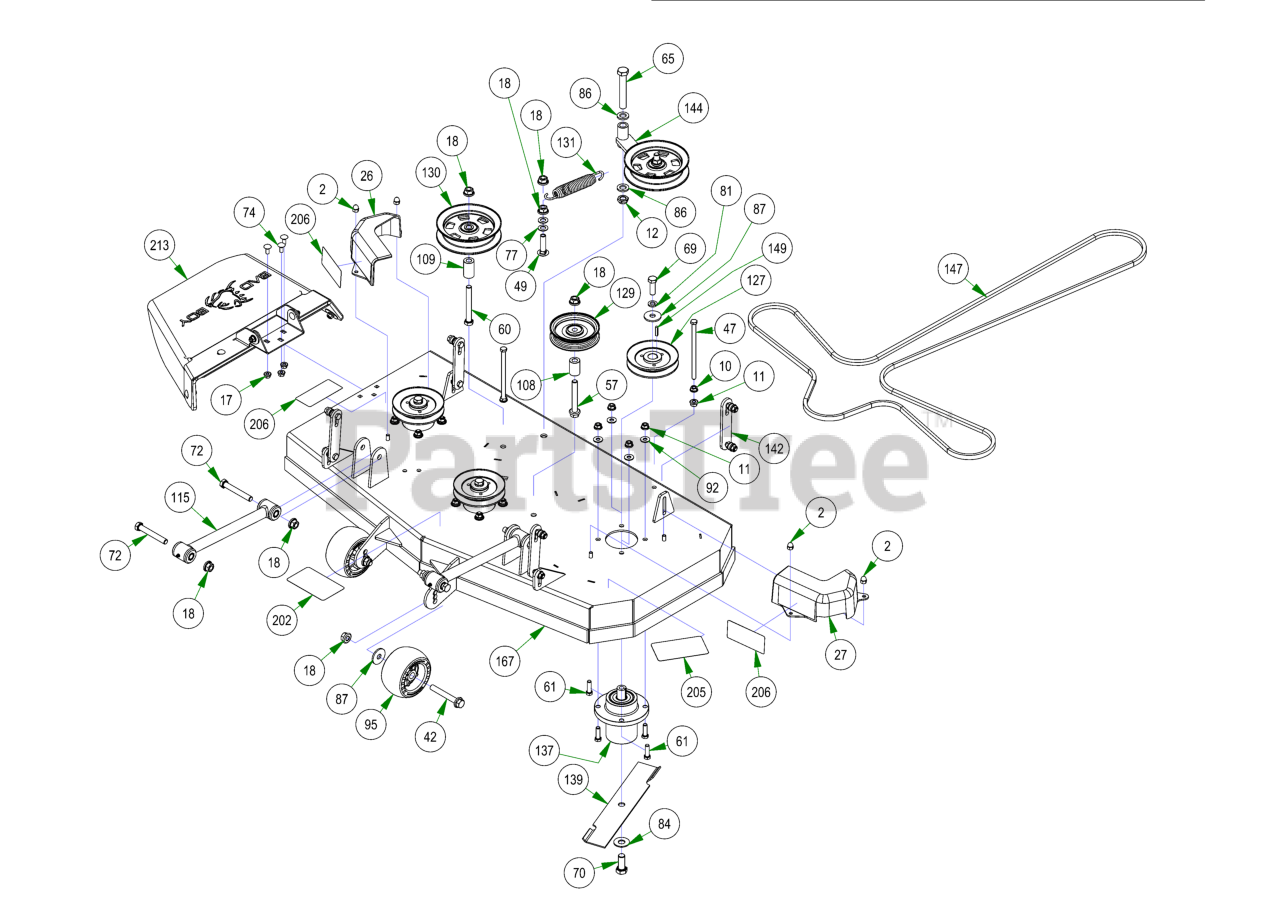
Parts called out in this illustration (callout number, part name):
2	5/16-18 ACORN NUT HIGH-CROWN ZC
10	3/8-16 HEX SERRATED FLANGE NUT HARD/ZINC
11	3/8-16 NYLON INSERT FLANGE LOCKNUT (GR.F) ZINC
12	5/8-11 NYLON INSERT JAM LOCKNUT ZINC
17	5/16-18 NYLON INSERT FLANGE LOCKNUT ZINC
18	1/2-13 NYLON INSERT FLANGE LOCKNUT ZINC
26	pulley cover chute side
27	pulley cover non-chute side
42	1/2-13 X 90MM HEX FLANGE BOLT W/SHOULDER (GR.8) ZINC
47	3/8-16 X 6.5 HEX CAP SCREW (GR.5) ZINC
49	1/2-13 X 2 CARRIAGE BOLT ZINC
57	1/2-13 X 3-1/2 HEX FLANGE BOLT (GR.8) ZINC
60	1/2-13 X 4 HEX CAP SCREW (GR.8) ZINC YELLOW
61	3/8-16 X 1-1/4 HEX CAP SCREW (GR.5) ZINC
65	5/8-11 X 4 HEX CAP SCREW (GR.8) ZINC YELLOW
69	1/2-20 X 1-1/2 HEX CAP SCREW (GR.5) ZINC
70	5/8-18 X 1-1/2 HEX CAP SCREW (GR.8) ZINC YELLOW
72	1/2-13 X 3-1/2 HEX CAP SCREW (GR.5) ZINC
74	5/16-18 x 3/4 Carriage Bolt
77	.517 SQ WDTH ID X .937 OD X .060 THICK F/W PHOS/OIL
81	1/2 SPLIT LOCKWASHER (GR.8) ZINC/YELLOW
84	5/8 USS FLAT WASHER (1-3/4" OD) GR.8 ZINC YELLOW
86	.635 ID X 1.120 OD X .140 THICK FLAT WASHER NYLON
87	1/2 BELLEVILLE WASHER (1-5/8 OD X .140 THK) ZINC
92	5/16 USS FLAT WASHER (7/8 OD) ZINC
95	Deck Wheel
108	.502 ID X .750 OD X 1.500 Long Spacer
109	1 3/4" Pulley Spacer
115	Hybrid Turnbuckle/Deck Locator
127	MZ Deck Pulley
129	4 3/4" Idler Pulley
130	5-3/4 Idler Pulley
131	Deck Idler Spring
137	Spindle Assembly-MZ
139	MZ 42 Blade
142	Deck Hanger Assembly
144	2017 54"/48" Deck Idler Assembly
149	3/16 X 1 SQ MACHINERY KEY 1018 STL ZINC
167	42" MZ Deck
202	2017 MZ Magnum 48"/42" Deck Route Decal
205	2018 42" MZ/Comp Out Deck Decal
206	Danger Decal-Spindle/Discharge
213	MZ Discharge Chute Assembly
